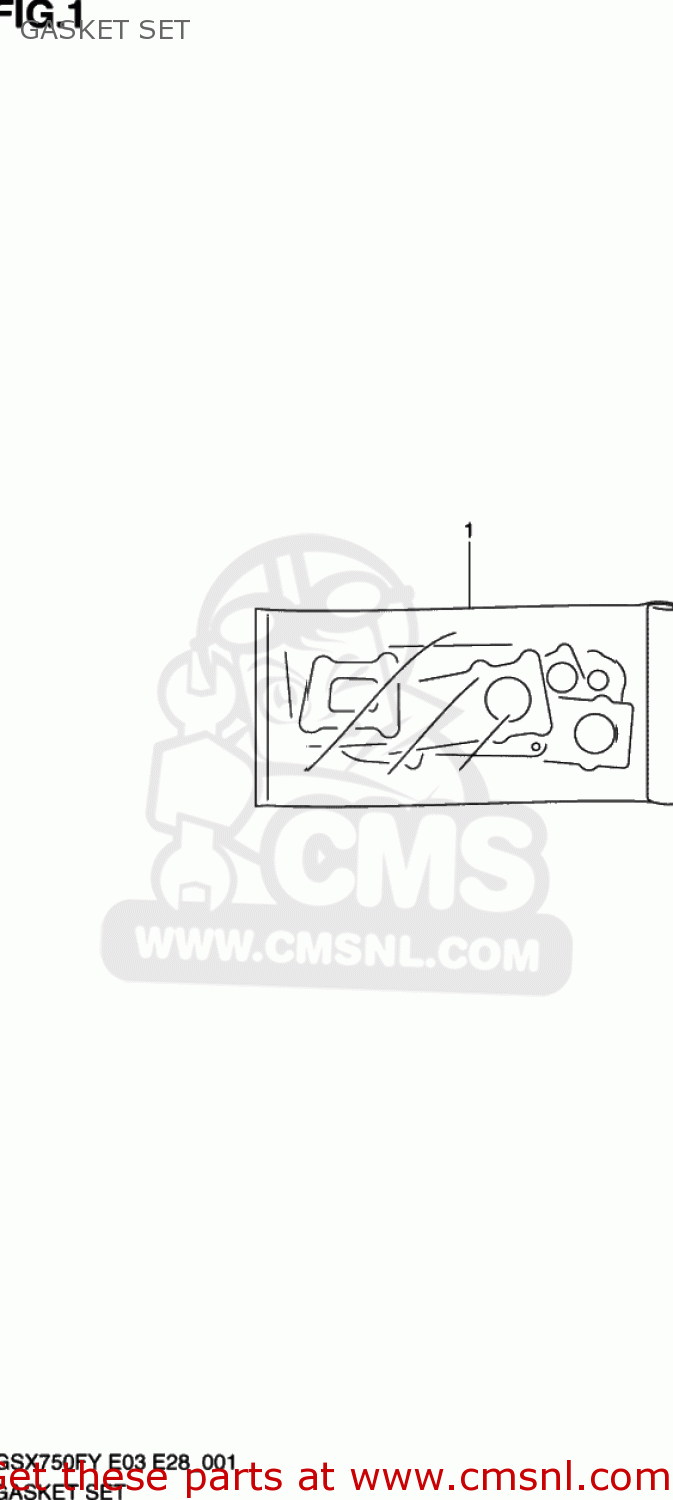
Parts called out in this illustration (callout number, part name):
1	GASKET SET (NAS)
2	GASKET,CYLINDER HEAD (NAS)
3	O RING,HEAD GASKET
4	GASKET,CYLINDER HEAD COVER (NAS)
5	GASKET,BREATHER COVER (NAS)
6	GASKET,HEAD COVER NO.2 (NAS)
7	GASKET,HEAD COVER NO.3 (NAS)
8	GASKET,CYLINDER (NAS)
9	GASKET,CL COVER (NAS)
10	GASKET,STARTER GEAR COVER (NAS)
11	GASKET,OIL PAN(ASB) (NAS)
12	GASKET,SIGNAL GEN COVER (NAS)
13	GASKET,TENSIONER ADJUSTER (NAS)
14	GASKET,EXHAUST (NAS)
15	O RING,OIL PUMP
16	GASKET,OIL STRAINER PROTECTOR (NAS)
17	GASKET,OIL OUTLET (NAS)
18	GASKET(5.8X11X1.2) (NAS)
19	GASKET 8.2X14X1 (NAS)
20	GASKET(8.5X17X2.3) (NAS)
21	GASKET(10.2X20X2).3 (NAS)
22	GASKET(14X19.2X2) (NAS)
23	GASKET(16X22X2) (NAS)
24	O RING(D:1.2,ID:4)
25	O RING(D:2.5,ID:13.8)
26	O RING(D:2.4,ID:15.8)
27	O RING(D:2.4,ID:16.8)
28	O RING(D:3.1,ID:16.8)
29	O RING(D:3.2,ID:17.8)
30	O RING(D:2.5,ID:21)
31	O RING(D:3.7,ID:21.7)
32	O RING(D:3,ID:24.5)
33	O RING(D:1,ID:24.5)
34	O RING(D:2.4,ID:36.5)
35	O RING(D:2.4,ID:41.7)
